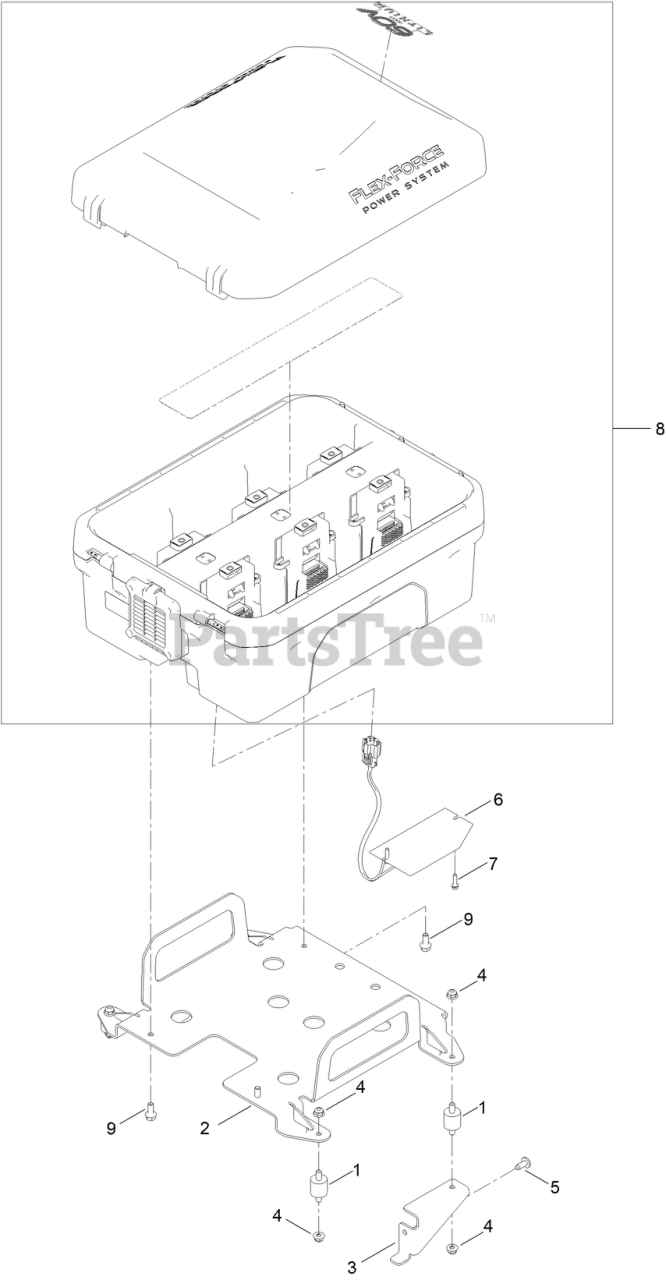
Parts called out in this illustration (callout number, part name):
1	ISOLATOR-1 IN OD (5/16-18)
2	BATTERY MOUNT ASM [RED]
3	MOUNT-BOX, REAR
4	NUT-HF
6	RESISTOR-REGEN
7	SCREW-HWH THD ROLL
8	BOX-BATTERY, ASM
9	SCREW-HHF
